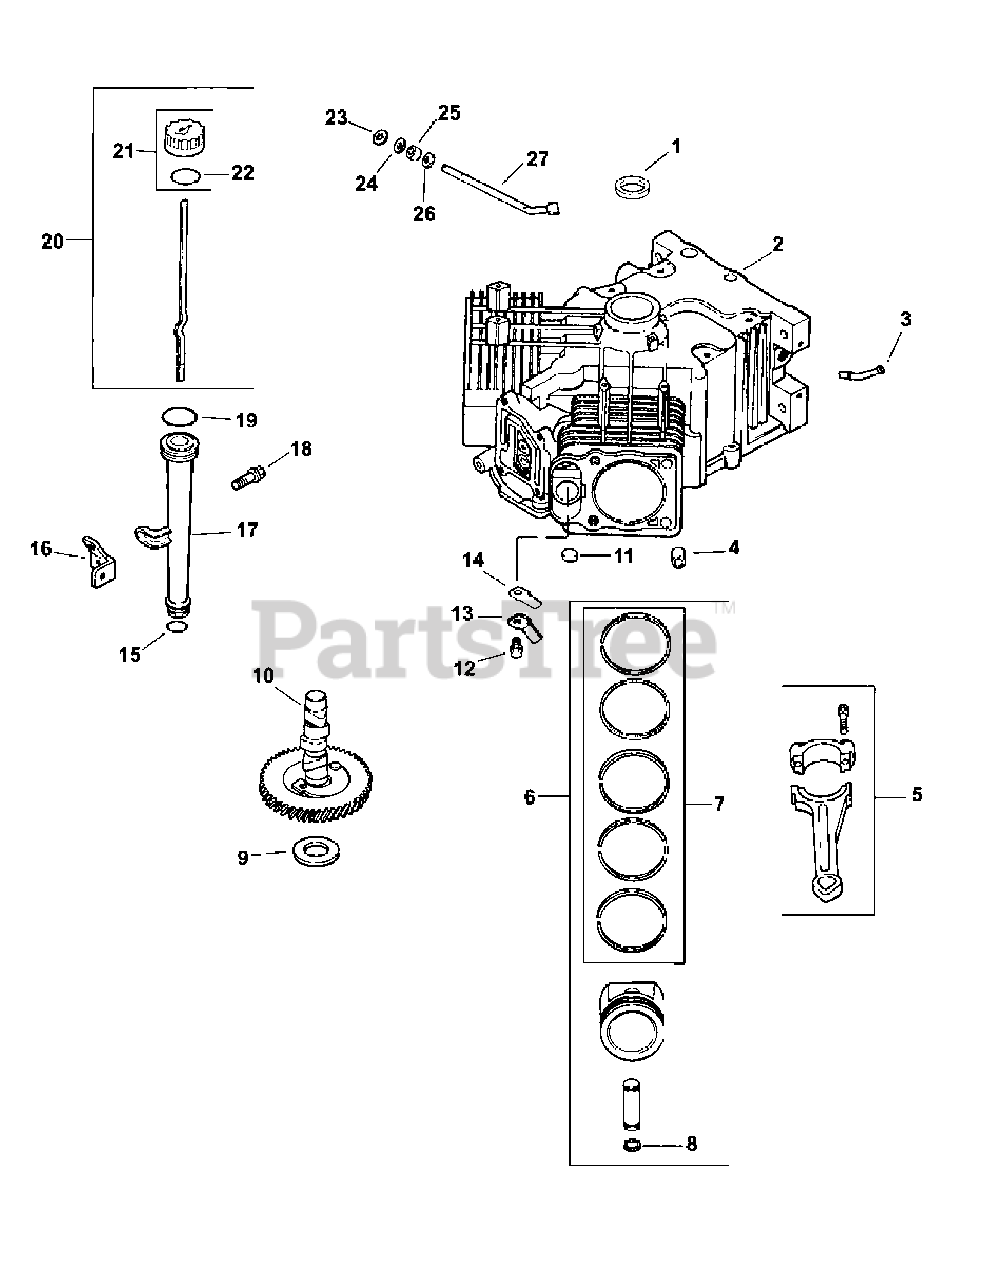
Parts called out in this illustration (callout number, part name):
1	Front Oil Seal
2	Crankcase
5	Connecting Rod (Std.)
5	Connecting Rod (.25)
6	Piston w/Ring Set (Std.)
6	Piston w/Ring Set (.08)
6	Piston w/Ring Set (.25)
6	Piston w/Ring Set (.50)
7	Ring Set (Std. & .08)
7	Ring Set (.25)
7	Ring Set (.50)
8	Piston Pin Retainer
9	Camshaft Shim-Red
9	Camshaft Shim-Black
9	Camshaft Shim-White
9	Camshaft Shim-Blue
9	Camshaft Shim-Yellow
9	Camshaft Shim-Green
9	Camshaft Shim-Gray
10	Camshaft
12	Hex Flange Screw
13	Reed Retainer
14	Breather Reed
15	Lower Oil Fill Tube O-Ring
16	Oil Fill Tube Bracket
17	Oil Fill Tube
18	Hex Flange Screw
19	Upper Oil Fill Tube O-Ring
20	Dipstick Assembly
21	Oil Fill Cap Kit
22	Dipstick O-Ring
23	Ring Retainer
25	Governor Cross Shaft Seal
27	Governor Cross Shaft
